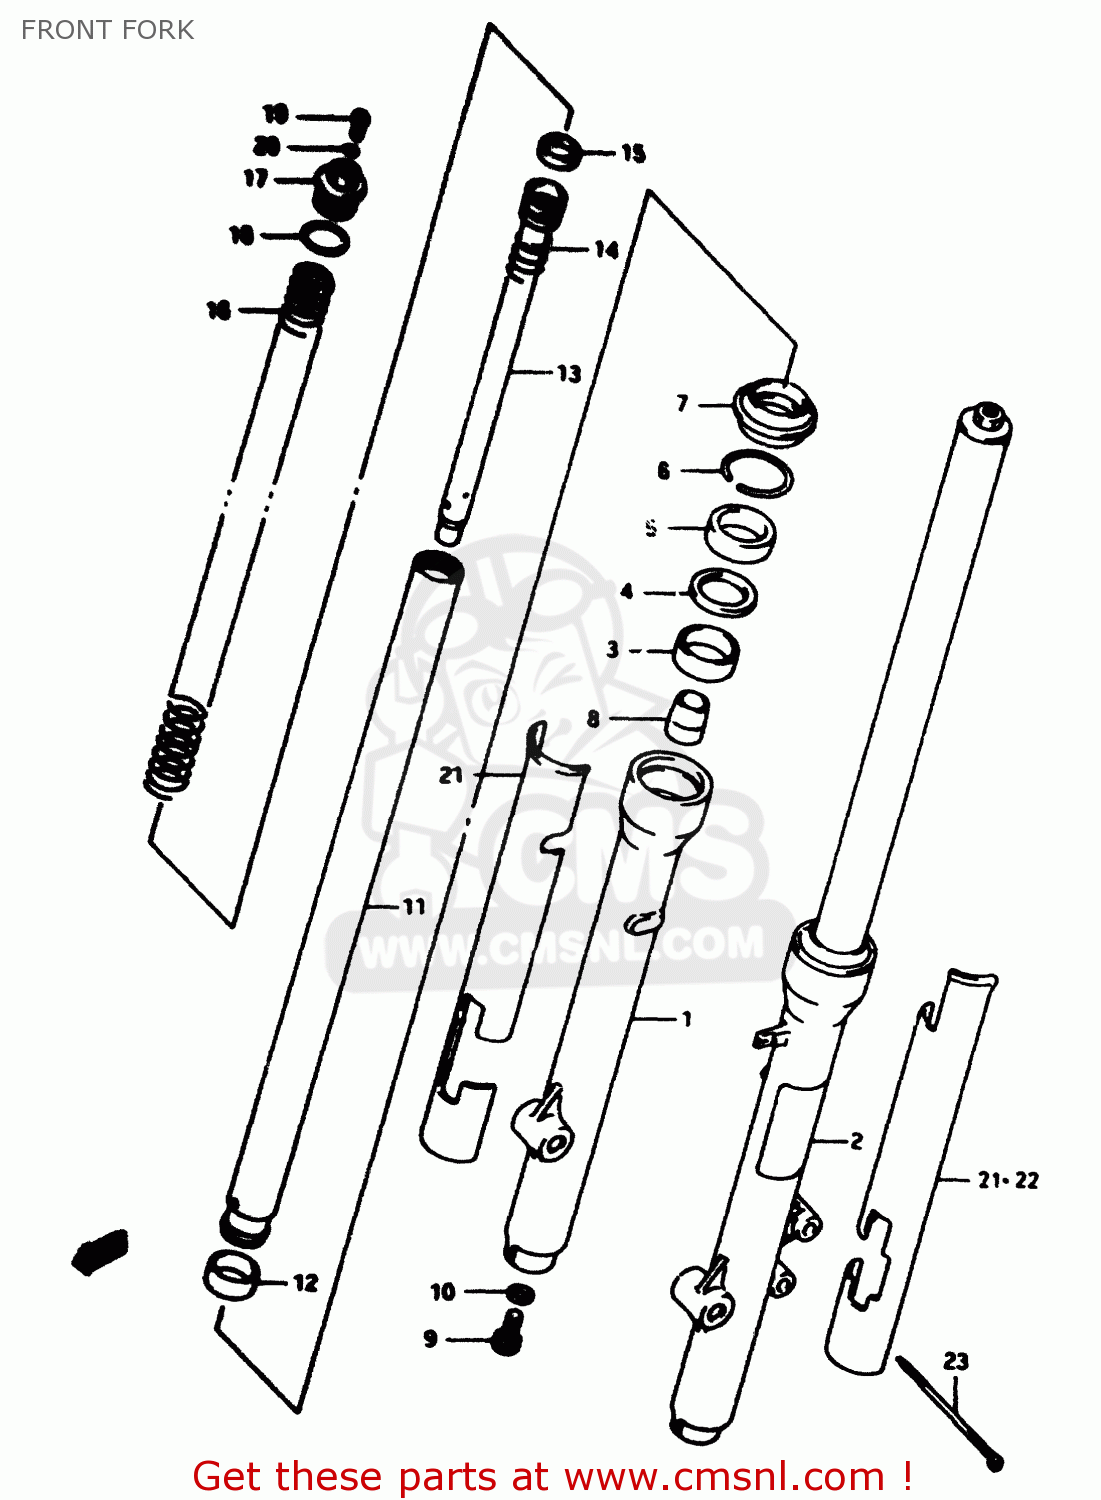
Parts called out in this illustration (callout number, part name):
1	TUBE,OUTER,R
2	TUBE,OUTER,L
3	BUSH,GUIDE
4	SPACER,SEAL
5	SEAL,OIL 35X48X11
6	RING,OIL SEAL STOPPER
7	SEAL,DUST
8	PIECE,OIL LOCK
9	BOLT(8X27)
10	GASKET (NAS)
11	TUBE,INNER
12	PISTON
13	SEAT,UNDER
14	SPRING,REBOUND
15	RING,PISTON
16	SPRING,UNDER
17	BOLT,FORK
18	O RING
19	BOLT,PLUG
20	O RING
21	PROTECTOR,FR FORK,R
22	PROTECTOR,FR FORK,L
23	CLAMP(L:250)
